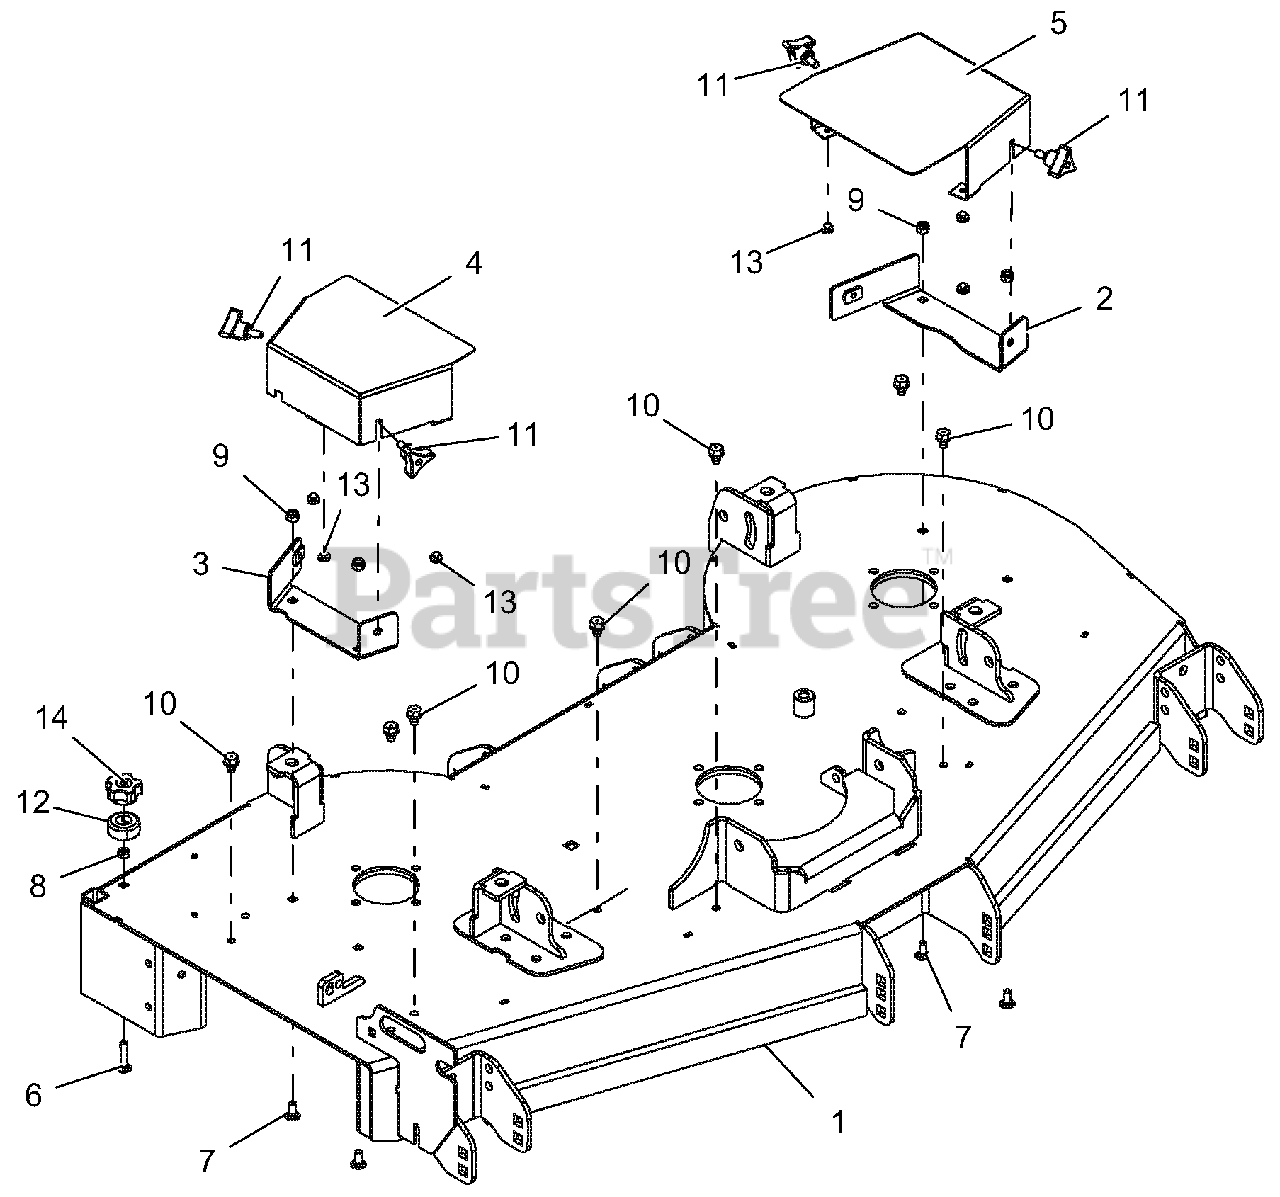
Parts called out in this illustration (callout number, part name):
1	KIT, 52 IN PROSTANCE MOWER DECK W/SAFETY DECALS
2	WLDMT, RH BRKT BELT GUARD MOUNTING-RED
3	WLDMT, LH BRKT BELT GUARD MOUNTING-RED
4	GUARD, RH DECK BELT
5	GUARD, LH DECK BELT-RED
6	BLT-RDHDSQNK .31-18X1.50 G5 YWZC
7	BLT-RDHDSQNK .31-18X.75 G5 YWZC
8	NUT-LK-CTR .31-18 YWZC
9	NUT-LK-NYL .312-18 YWZC
10	SCR-TAP .38-16X.50 HWH TR YWZ
11	KNOB, WING STUD .312-18X.75
12	BUMPER, RECESSED 1.50 X .63 W/.31 HOLE
13	BUMPER GROMMET .125 X .25 REV
14	KNOB, CLAMPING
